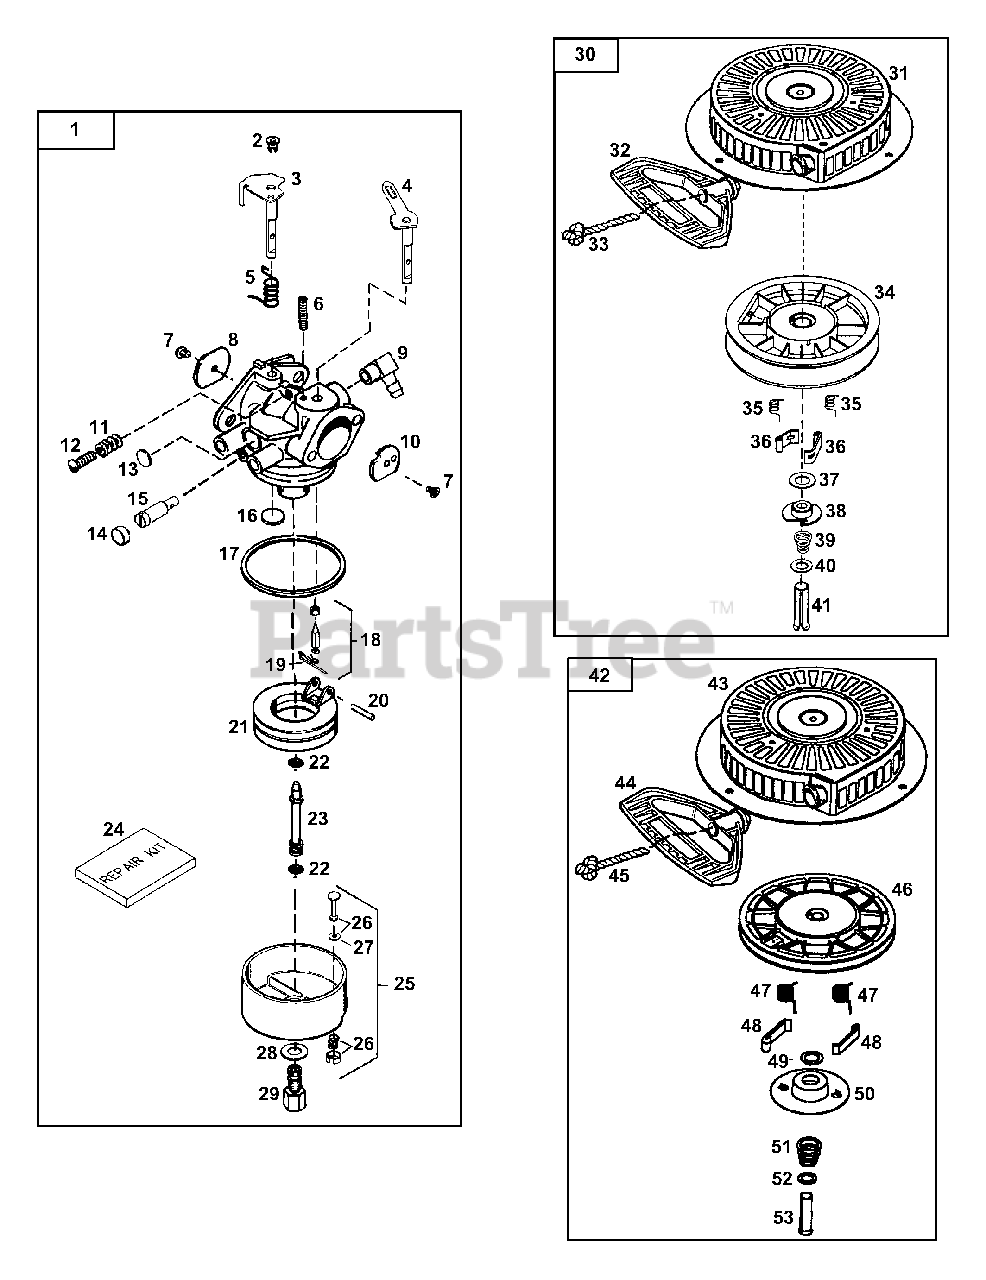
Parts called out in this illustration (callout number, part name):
1	Carburetor Assembly
2	Throttle Link Bushing
3	Throttle Shaft & Lever Assembly
4	Choke Shaft & Lever Assembly
5	Throttle Return Spring
6	Choke Positioning Spring
7	Shutter Screw
8	Throttle Shutter
9	Fuel Fitting
10	Choke Shutter
11	Tension Spring
12	Throttle Crack Screw/Idle Speed Screw
13	Welch Plug, Idle Mixture Well
14	Idle Restrictor Screw Cap
15	Idle Restrictor Screw
16	Welch Plug, Atmospheric Vent
17	Float Bowl O- Ring
18	Inlet Needle, Seat & Clip
19	Spring Clip
20	Float Shaft
21	Float
22	O- Ring, Main Nozzle Tube
23	Main Nozzle Tube
24	Repair kit
25	Float Bowl Assembly
26	Bowl Drain Assembly
27	Drain Plunger Gasket
28	Bowl Nut Washer
29	High Speed Bowl Nut
30	Rewind Starter
31	Starter Housing Assembly
32	Mitten Grip Handle
33	Starter Rope (Length 98" x 9/64" dia.)
34	Pulley & Rewind Spring Assembly
35	Dog Spring
36	Starter Dog
39	Brake Spring
41	Spring Pin
42	Rewind Starter Ass'y
43	Starter Housing Ass'y
44	Mitten Grip Starter Handle
45	Starter Rope (98")
46	Pulley & Rewind Spring Ass'y
47	Dog Spring
48	Starter Dog
51	Brake Spring
53	Spring Pin
